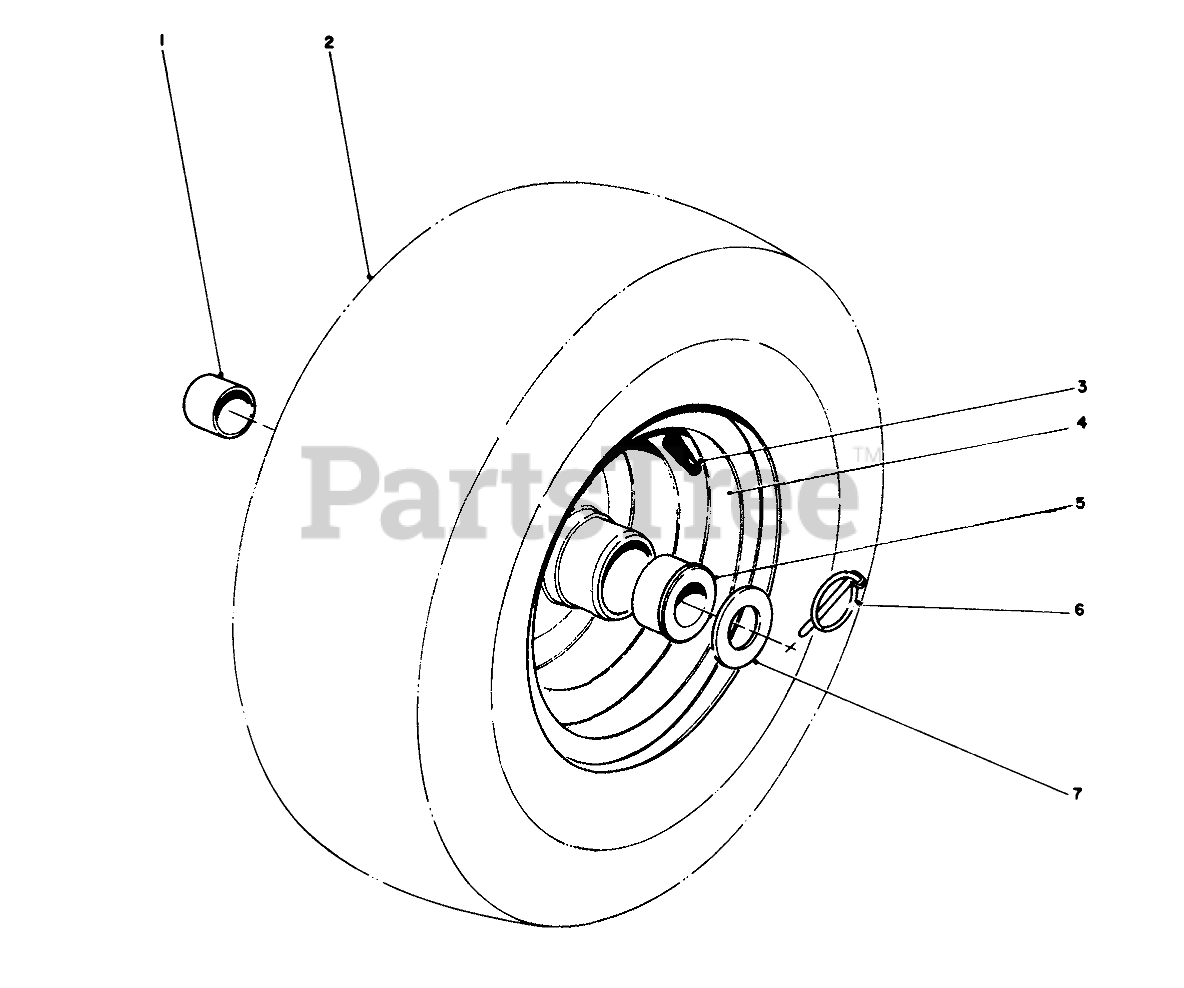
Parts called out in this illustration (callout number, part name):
1	.877ID X .750LG BSHG
2	Tire
3	STEM-VALVE
4	Wheel & Hub Assembly (Incl. Ref. #1 & 5)
5	BUSHING
6	PIN-LYNCH
7	WASHER-THRUST
